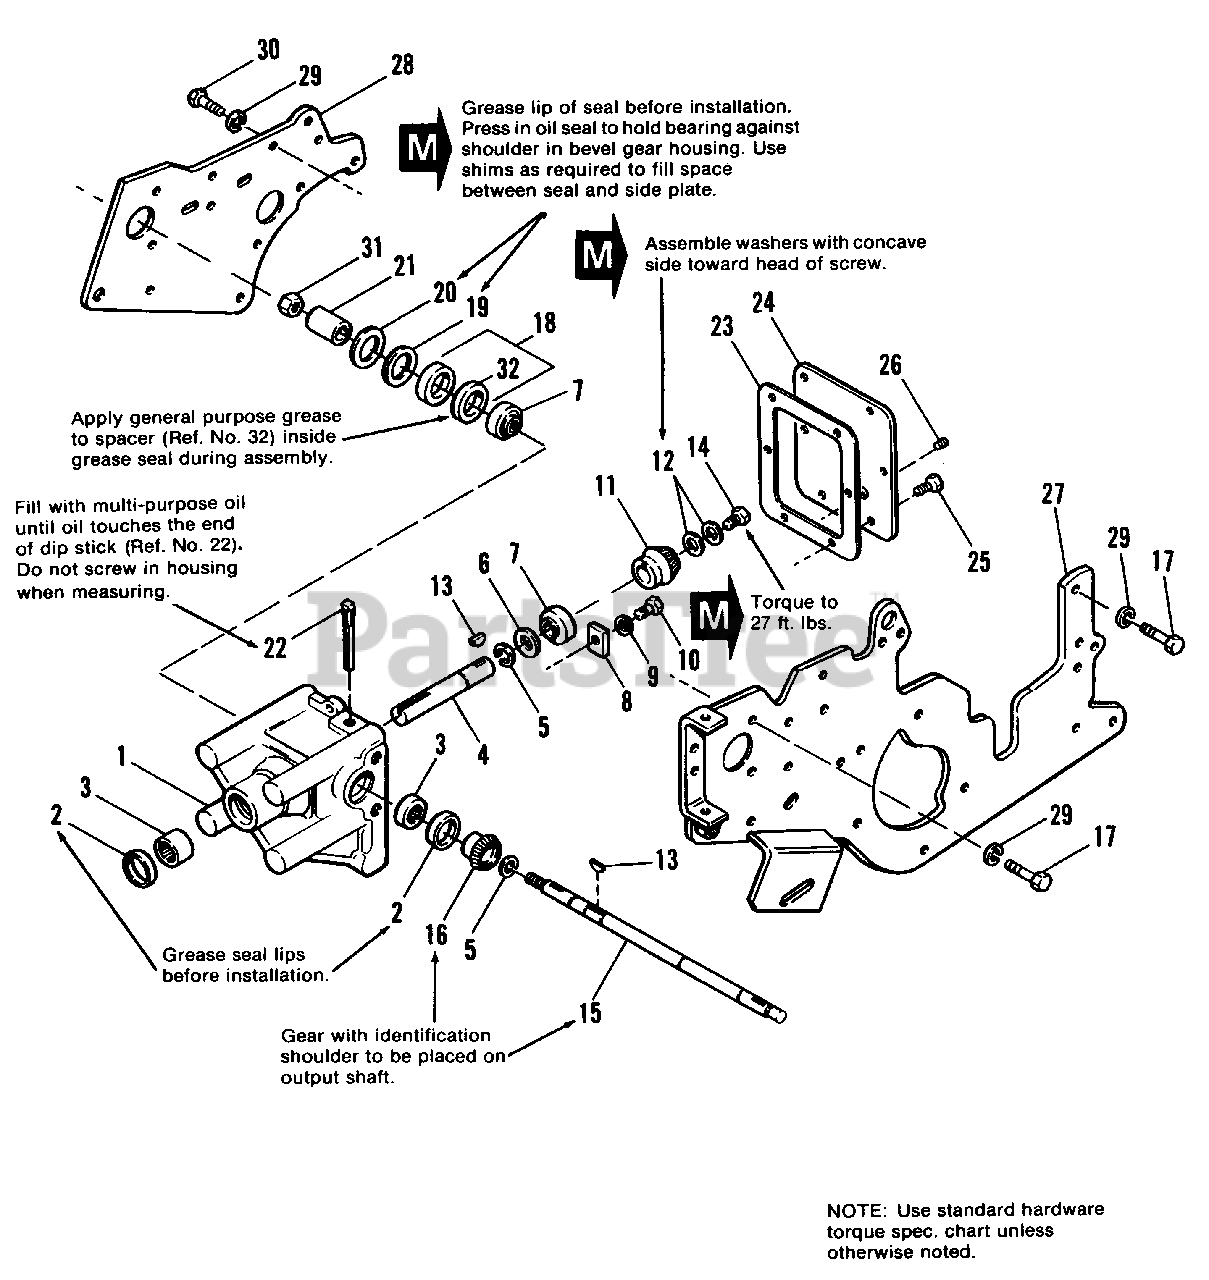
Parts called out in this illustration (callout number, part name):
1	HOUSING, Bevel Gear
3	BEARING, Needle
4	SHAFT, Driver
5	RING, Retaining
7	BEARING, Ball
8	PLATE, Bearing Clamp
9	LOCKWASHER, 5/16
10	CAPSCREW, Hex Hd., 5/16-18 x 5/8
11	GEAR, Bevel Driver
13	KEY, Woodruff #9
14	CAPSCREW, Hex Hd., 5/16-18 x 3/4
15	SHAFT, Driven
16	GEAR, Bevel Driven
17	CAPSCREW, Hex Hd., 7/16-14 x 1-1/4
18	SEAL, Oil Kit
25	CAPSCREW, Hex, 1/4-20 x 5/8
27	PLATE ASSY., Side, L.H.
28	PLATE ASSY., Side, R.H.
29	LOCKWASHER, 7/16
30	CAPSCREW, Hex Hd., 7/16-14 x 1
31	LOCKNUT, Hex, Jam, 3/4-16
32	SPACER, Oil Seal
